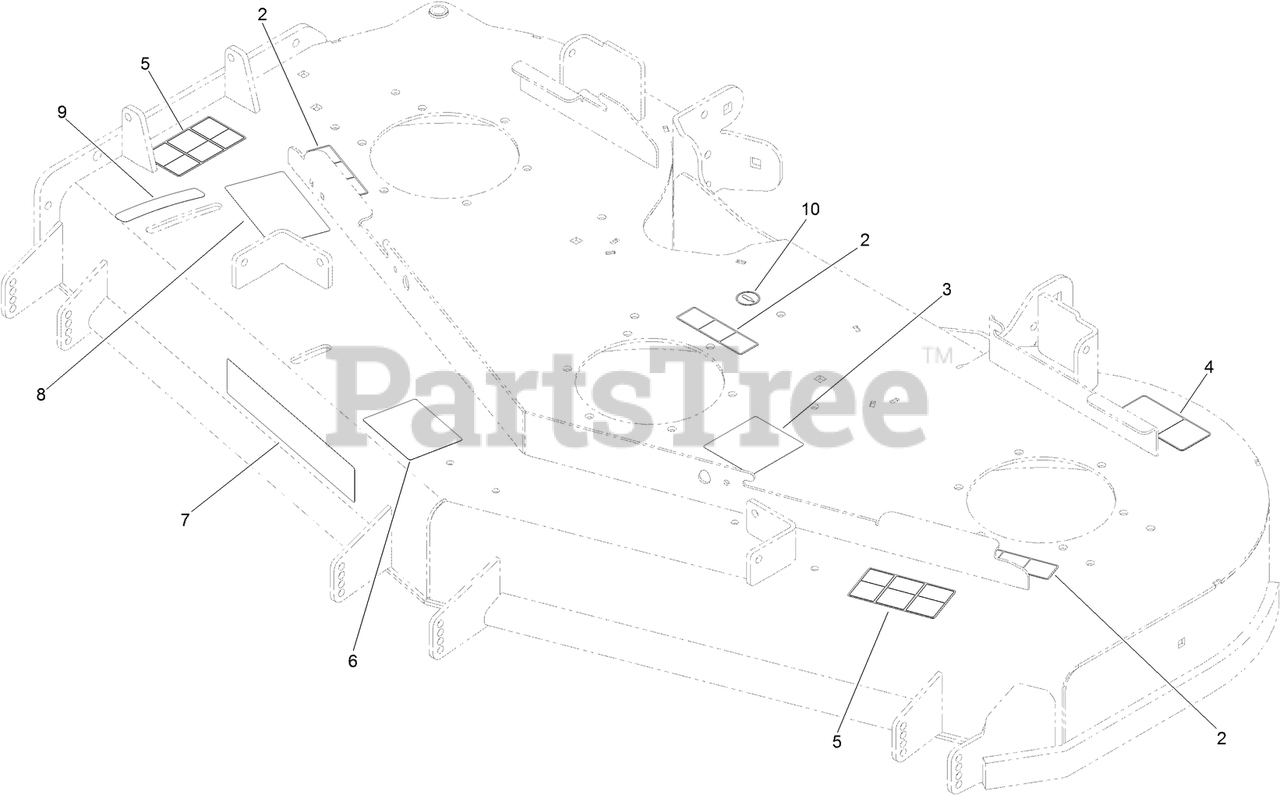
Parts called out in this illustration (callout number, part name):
2	DECAL-MISSING, COVER
3	DECAL-ROUTING, DECK BELT
4	DECAL-TORQUE, BLADE BOLT
5	DECAL-DANGER
6	DECAL-SCALP, ANTI
8	DECAL-ADJUSTMENT, BAFFLE
9	DECAL-SETTING, BAFFLE
10	DECAL-GREASE
